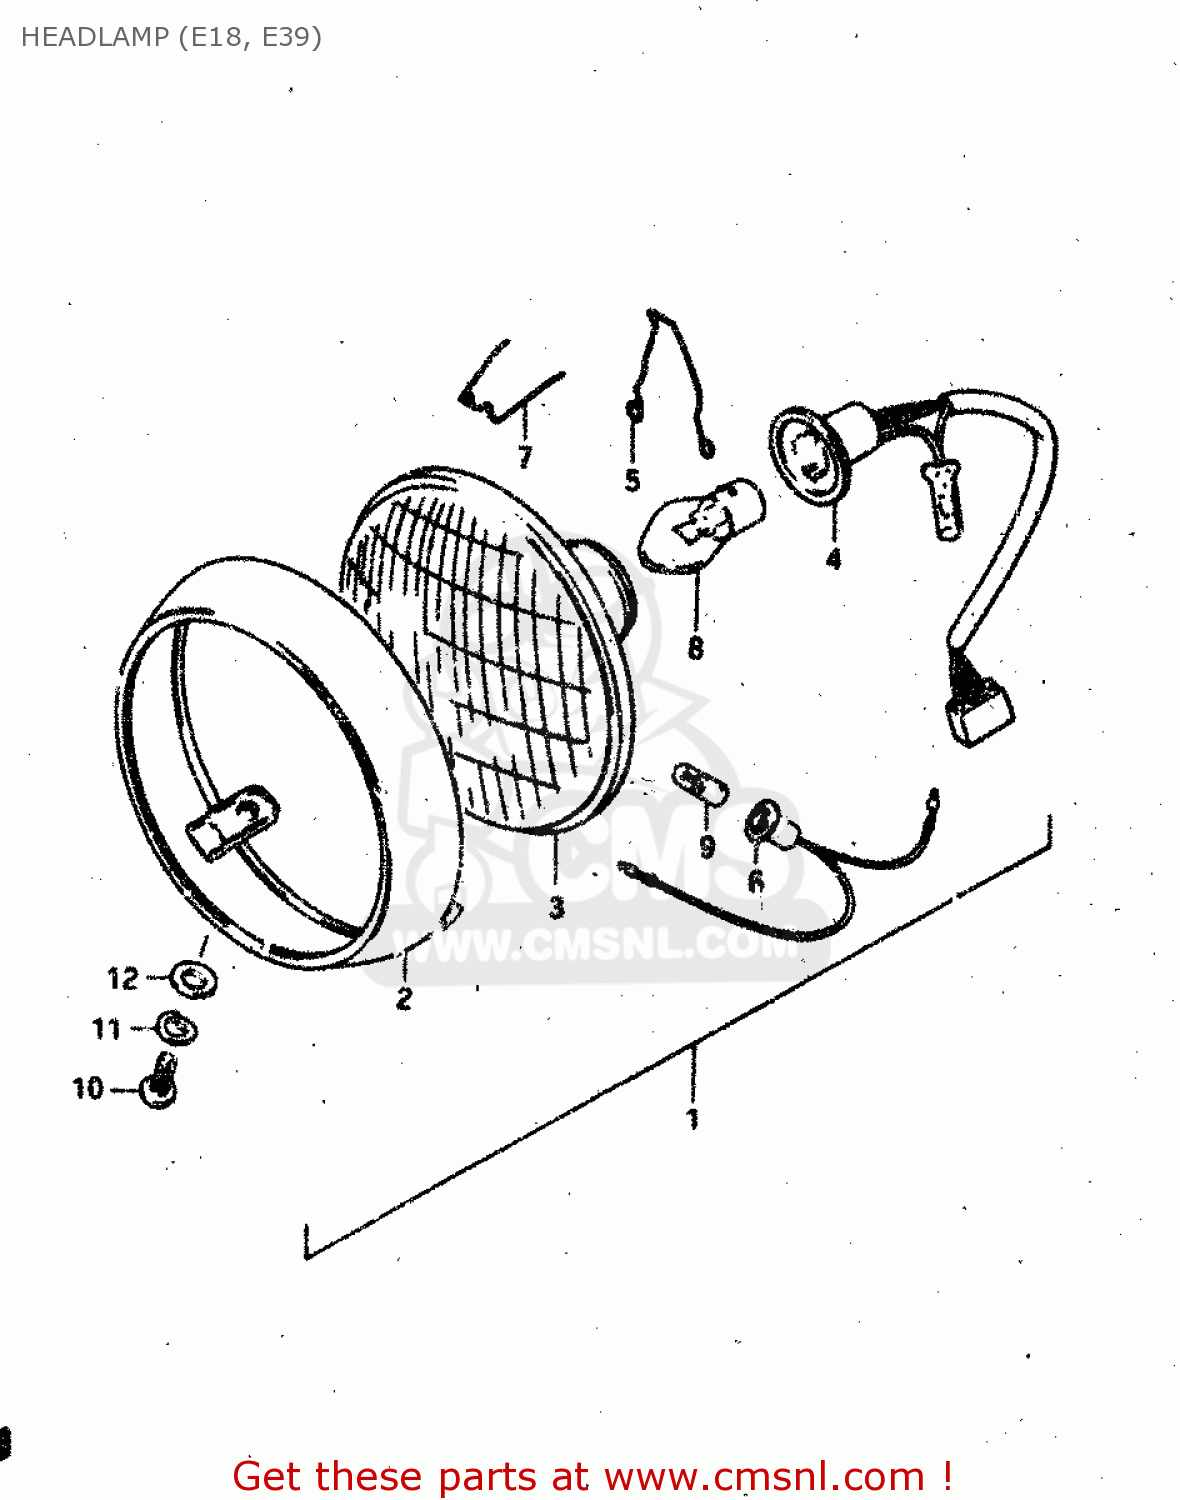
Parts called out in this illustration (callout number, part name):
1	HEADLAMP ASSY
2	RIM
3	UNIT
4	SOCKET
5	CLAMP,HEADLAMP
6	SOCKET
7	SPRING
8	BULB (6V,25/25W)
9	BULB (6V,4W)
10	SCREW
11	LOCK WASHER
12	WASHER
